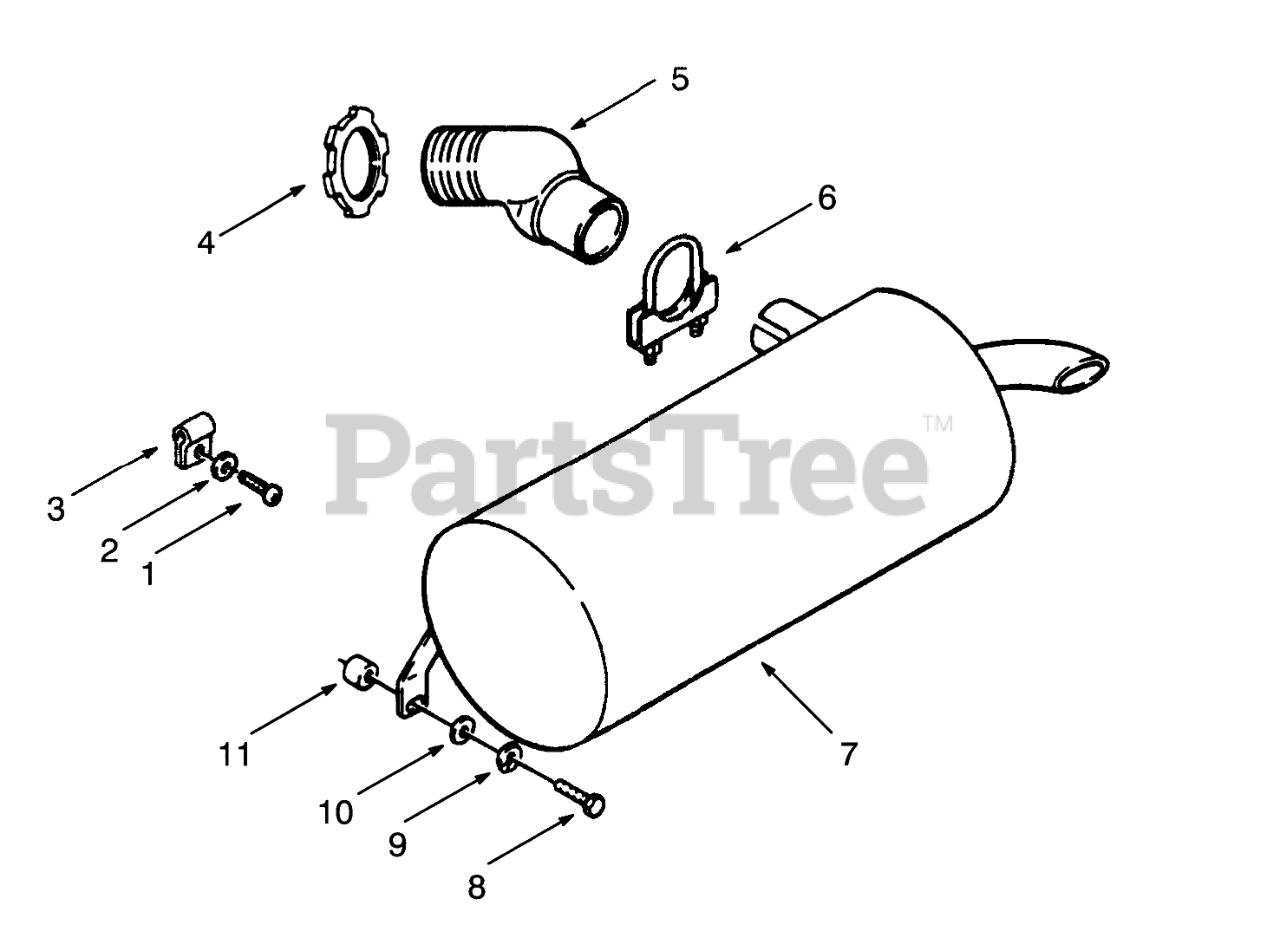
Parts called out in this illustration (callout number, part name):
1	Screw
2	Washer
4	Nut-Lock
5	Elbow
6	CLAMP-1 1/2
7	Muffler
8	SCREW-HH
9	WASHER-LOCK
10	WASHER-FLAT
11	SPACER
